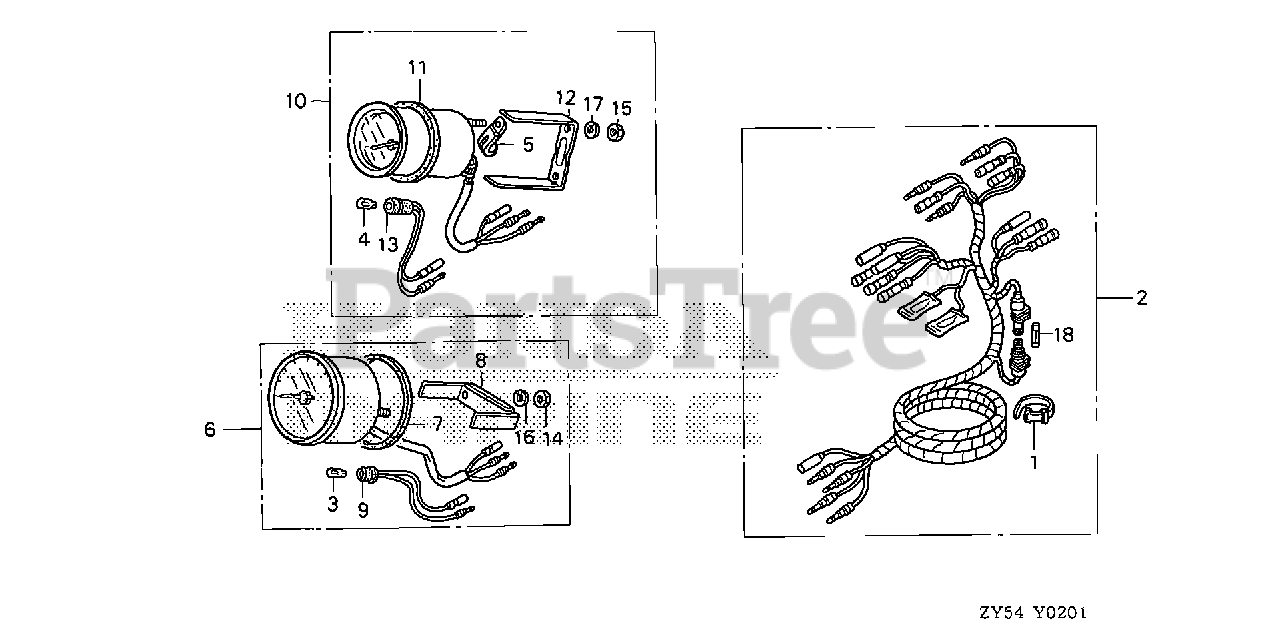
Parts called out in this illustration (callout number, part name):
1	BAND B1, WIRE
2	HARNESS ASSY., METER (A)
3	BULB, WEDGE BASE (T10) (12V 1.7W) (STANLEY)
4	BULB, WEDGE BASE (12V 1.7W)
5	CLAMP
6	TACHOMETER ASSY.
7	GASKET
8	BRACKET
9	SOCKET
10	METER ASSY., TRIM
11	GASKET
12	BRACKET
13	SOCKET
14	NUT, HEX. (5MM)
15	NUT, HEX. (4MM)
16	WASHER, SPRING (5MM)
17	WASHER, SPRING (4MM)
18	FUSE A (10A)
